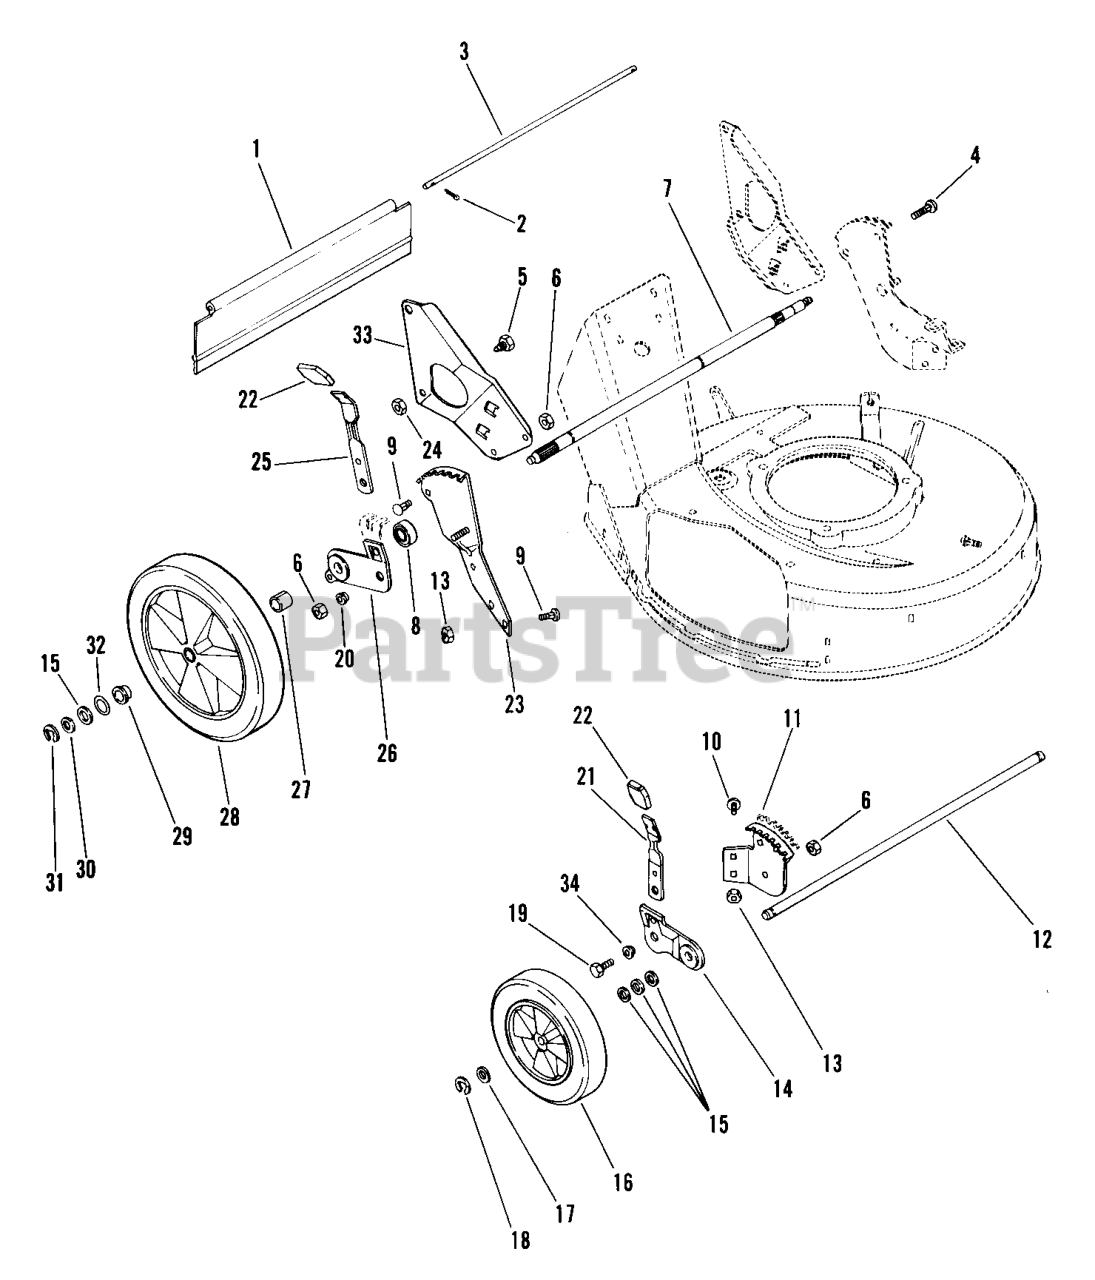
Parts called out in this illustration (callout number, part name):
1	REAR PROTECTIVE GUARD, PUSH
1	REAR PROTECTIVE GUARD, S.P.
2	PIN-COTR .06X.50
3	ROD
4	BLT-RDHDSQNK .31-18X1.0 SHT PL
4	BLT-RDHDSQNK .31-18X1.25 SHTPL
5	HANDLEBAR STUD
6	NUT-LK .312-18 GR A PL
7	REAR AXLE,5/8 DIA
7	REAR AXLE - PUSH MOWER
9	BLT-RDHDSQNK .312-18X.62SHTPL
10	BLT-RDHDSQSHNK .31-18X.50 YZ
11	FRONT QUADRANT, L.H.
11	FRONT QUADRANT, R.H.
12	FRONT AXLE
13	NUT-FLG. .312-18 PL
14	LEFT ADJUSTOR BRACKET ASSEMBLY
14	RIGHT ADJUSTOR BRACKET ASSEMBL
15	WSHR-FL-STL .520X.827X.062 YZ
16	WHEEL
17	WSHR-FL-STL .505X.880X.072 PL
18	RG-RTNG-EXT .438X.035
19	BLT-HEX .31-18X.88 PL GR2
20	BSHG-FLG .32X.500X.344X.880
21	FRONT HEIGHT ADJUSTMENT LEVER
23	QUADRANT, REAR - L.H.
23	REAR QUADRANT, R.H.
24	NUT-LK-JAM-CTR .375-16 PL
25	HEIGHT ADJUSTMENT LEVER
26	REAR BRACKET & BEARING ASSEMBL
26	REAR BRACKET & BEARING ASSY RH
26	REAR ADJUSTMENT BRACKET L.H.
27	SPACER TUBE,PUSH LH
27	SPACER TUBE PUSH RH
27	SPACER TUBE, SELF PROPEL
28	WHEEL
28	LH WHEEL
28	RH WHEEL
28	10 1/2 TIRE SKIN
29	BSHG-SLV .625X.750X.500
30	WSHR-FL-STL .630X1.005X.062 PL
31	RG-RTNG-EXT .500X.042 (E)
32	SEAL .625X.875X.125
33	RH HANDLEBAR MTG. BRKT.
33	LH HANDLEBAR MTG. BRKT.
34	BSHG-FLG .32X.500X.344X.880
